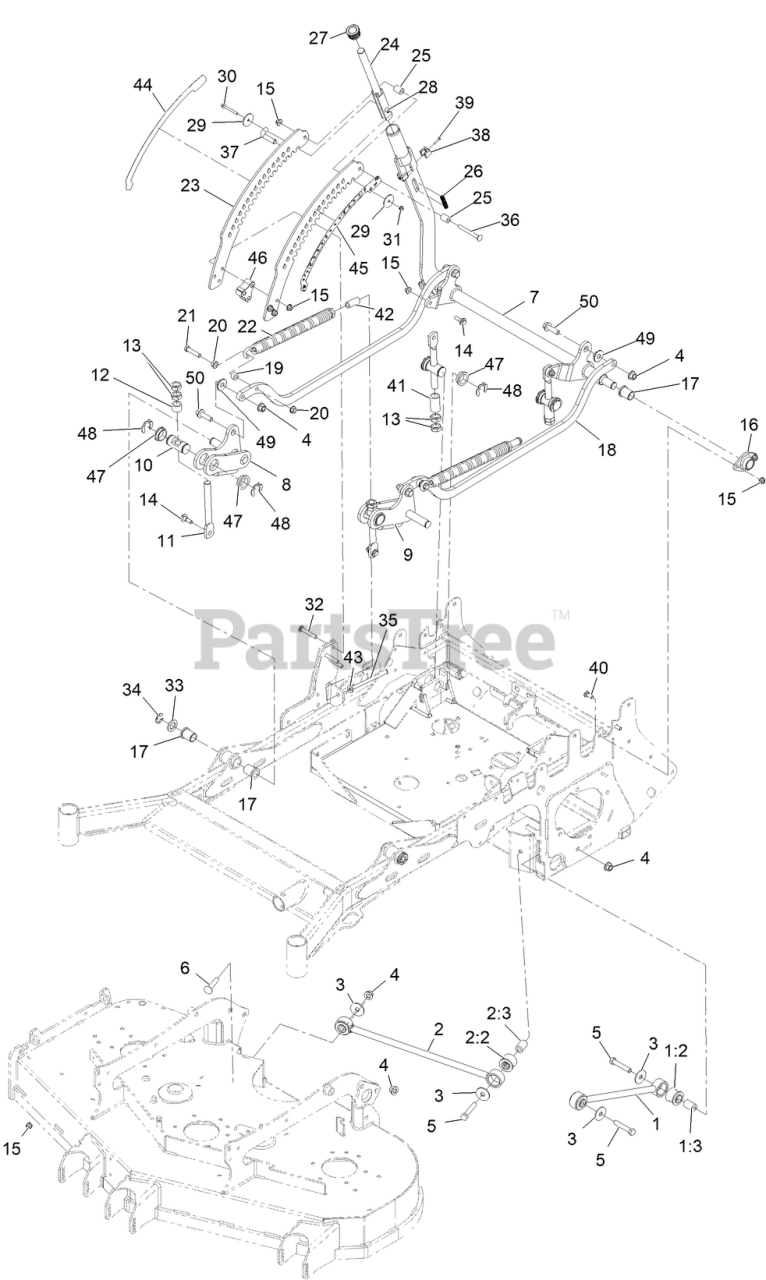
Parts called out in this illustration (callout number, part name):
1	ASM, DECK STRUT
1:2	BUSHING-RUBBER
2	PANHARD ROD ASM
2:2	BUSHING-SUSPENSION, RUBBER
3	WASHER-THRUST
4	Nut-Lock 1/2-13
5	SCREW-HH
6	SCREW-CARR
7	CROSS SHAFT -DECKLIFT-REAR
8	WELD-ARM-DECKLIFT-FRONT-RH
9	WELD-ARM-DECKLIFT-FRONT-LH
10	TRUNION-DECKLIFT GROOVED
11	Link,Deck Lift Adjuster
12	SPACER-DECKLIFT
13	NUT-JAM
14	SCREW-SHOULDER, HHF
15	NUT-HF, NI
16	Support-HOC Shaft
17	BUSHING-FLANGED
18	LINK-HOC 52-60
21	SCREW-HH
22	SPRING-EXTENSION
23	PLATE-HOC
24	ASM-PLUNGER-HOC
25	TUBE-INTERLOCK
27	PLUG-PLASTIC HOC
29	SPACER-HOC
30	SCREW-HHF
32	SCREW-CARR
34	RING-RETAINING, EXT
35	BOLT-TAP, HH
36	SCREW-CARR
37	PIN-HOC
38	CHANNEL-HOC GUIDE
39	SCREW-SHWH
40	SCREW-CARR
41	SPACER 1.13 O.D. X .81 I.D. X 2.05L
42	SPACER-HOC
44	DECAL-HEIGHT OF CUT,OUTER
45	DECAL-HEIGHT OF CUT-INNER
46	SPACER-HOC VERTEX
47	BUSHING-FLANGED HOC
48	E-RING WIDE GRIP
50	SCREW-HHF
